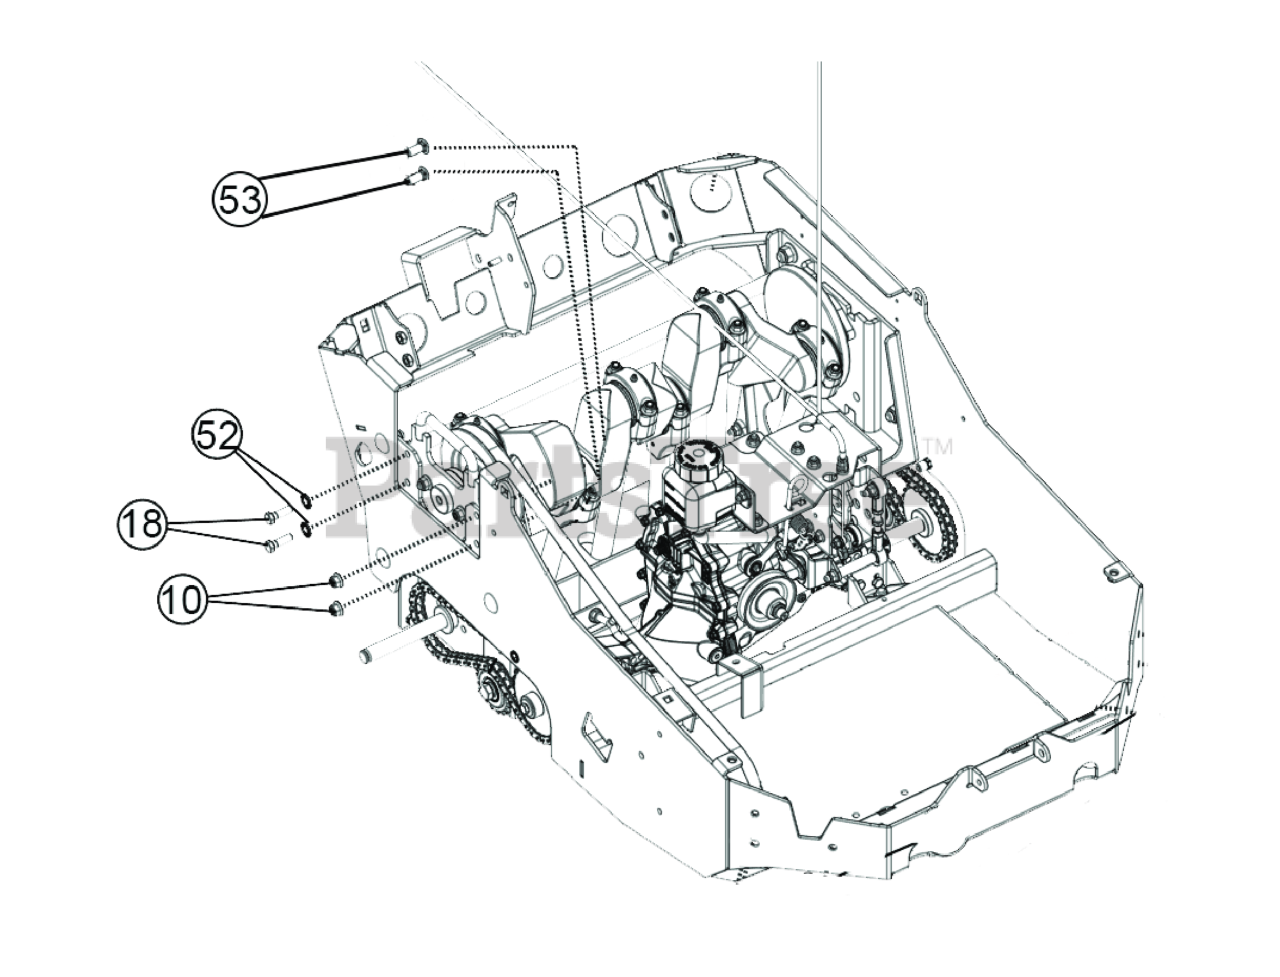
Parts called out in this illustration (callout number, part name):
10	NUT-HEX-NYLK, FLG .375"-16 ZP
18	SCREWCAP 3/8"-16X1 1/4" HCS ZP
52	WSHR-STL, BLV, .402 X .877 X .063 CN MZ
53	BOLT CARRAIGE 3/8-16 X 1" ZP
